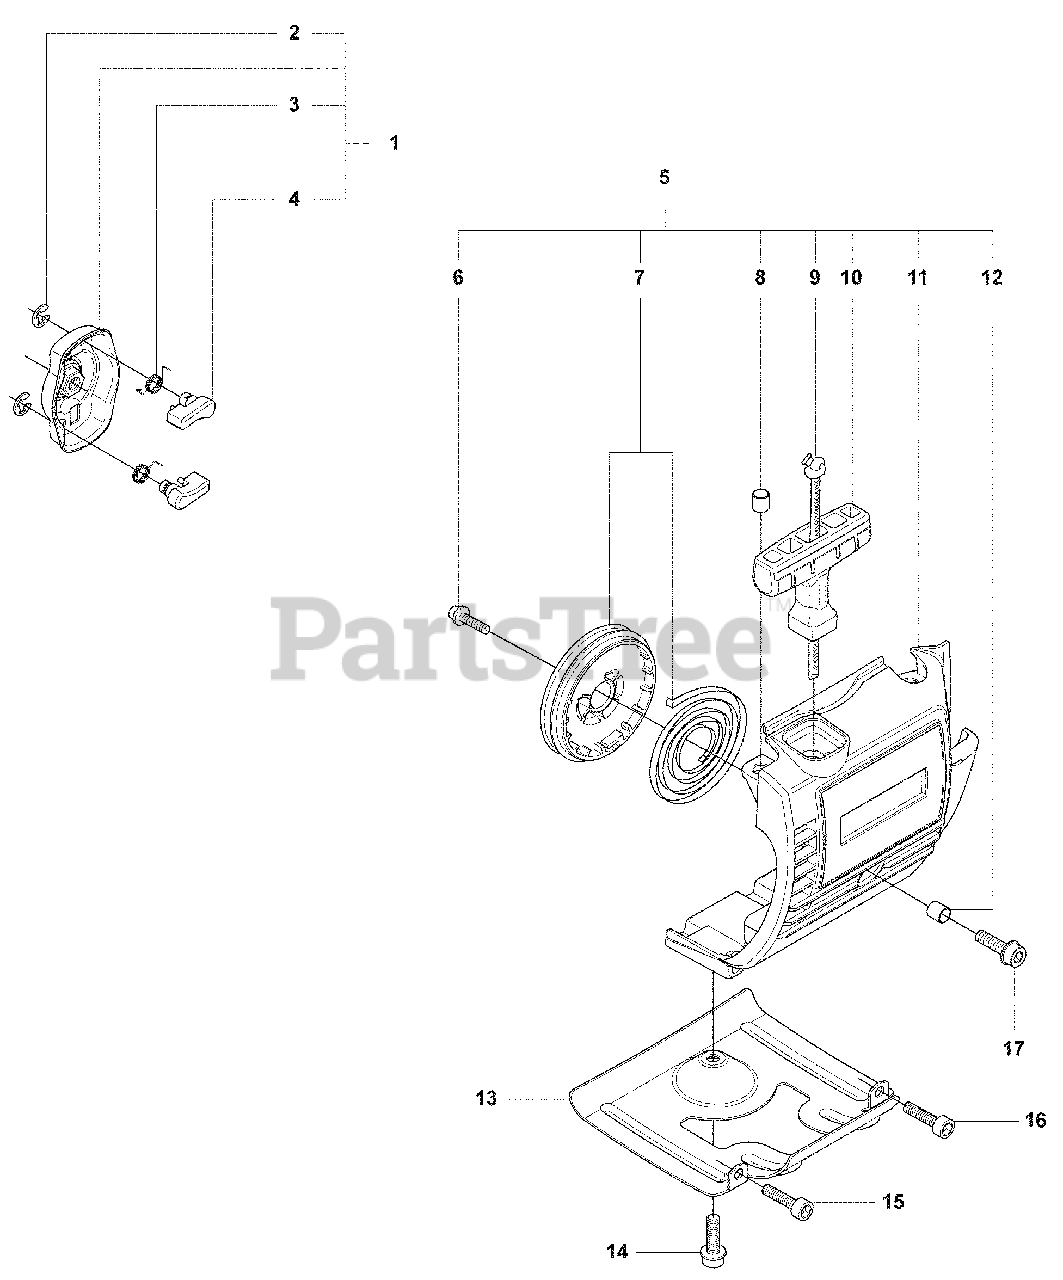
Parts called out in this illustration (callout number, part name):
1	Starter Pawl Bridge
2	Bar Retainer
4	Starter Pawl
5	Starter Assembly
7	Starter Pulley Assembly
8	Spacing Sleeve
9	Starter Rope
10	Starter Handle
11	Starter Housing
12	Spacing Sleeve
14	Screw, M5 X 12 Ms Hcs Ih X
17	Screw
